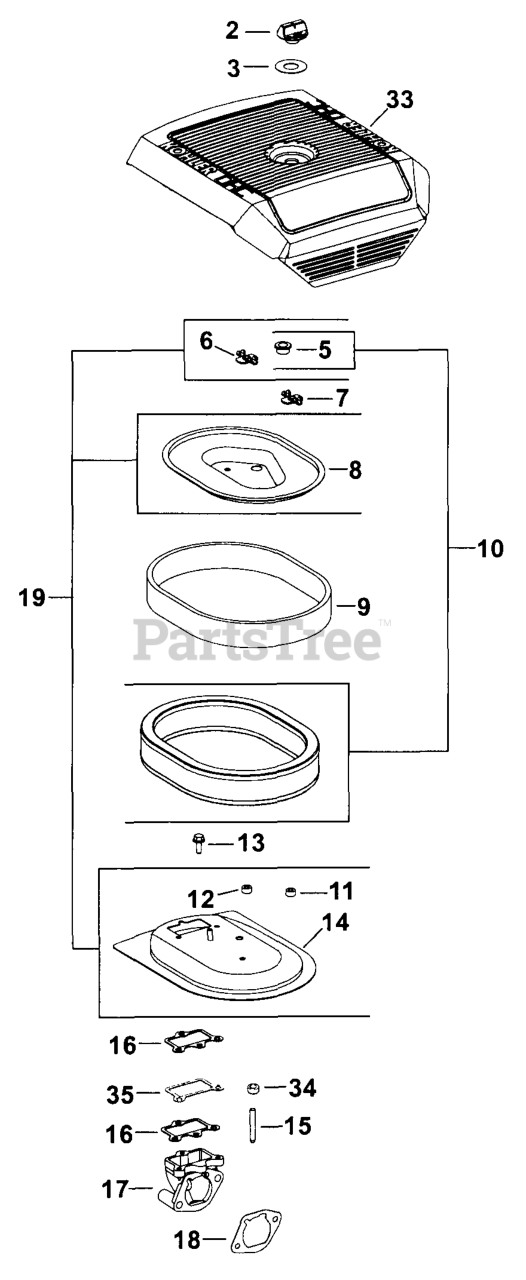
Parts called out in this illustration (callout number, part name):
2	KNOB, COVER
3	GASKET, AIR CLEANER COVER KNOB
5	SEAL, CARB ADJUST SCREW
6	NUT, WING - (#DSC)
7	NUT, WING
8	Cover, inner air cleaner element
9	ELEMENT, PRE-CLEANER
10	ELEMENT KIT, AIR FILTER
11	SEAL, INNER AIR CLEANER
12	SEAL - DISCONTINUED
13	SCREW,FLG THD FRM M6X1.0X20-(#25086396S)
14	Base, air cleaner
15	STUD - DISCONTINUED
16	GASKET, AIR CLEANR BASE
17	ELBOW, AIR CLEANER
18	GASKET, AIR CLEANER BASE
19	KIT, AIR COVER BASE - (#DSC)
33	COVER, AIR CLEANER-DISCONTINUED
35	SPACER, AIR CLEANER BASE
